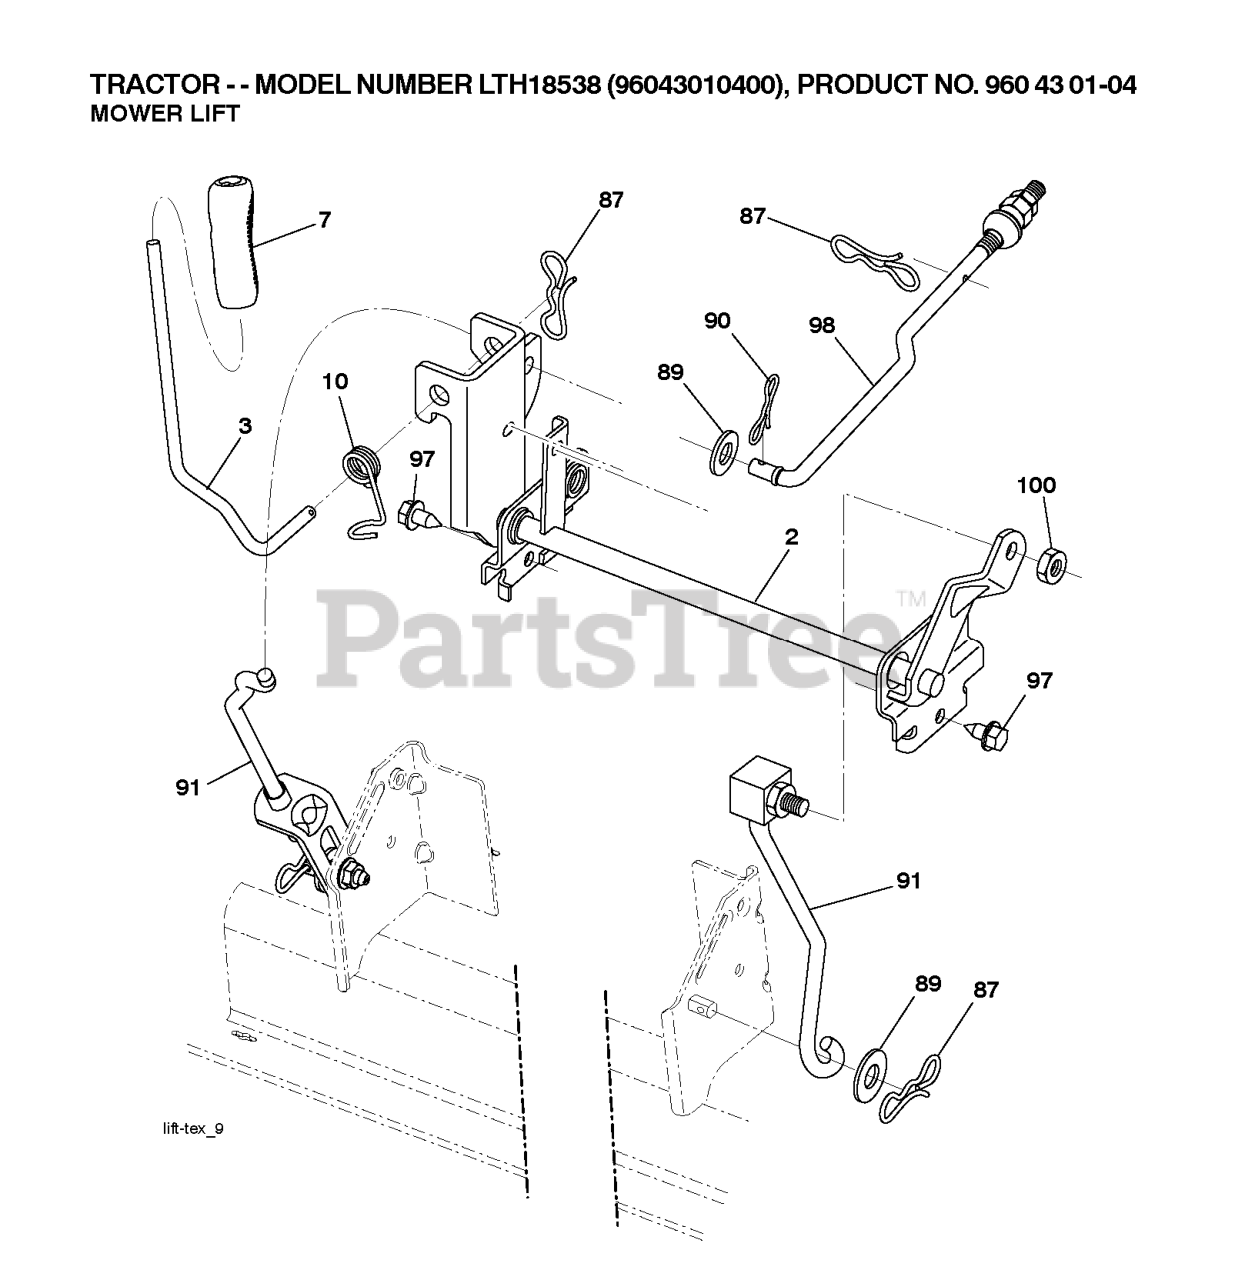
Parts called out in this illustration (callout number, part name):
2	SHAFT.ASM.CROSS.LIFT
3	LEVER.LIFT.HANDLE.LT
7	GRIP.HANDLE.LIFT.PVC.BLACK
10	SPRING.TORSION.LIFT.HANDLE
87	PIN.COTTER.7/16.BOW TI.
89	WASHER.CLEAR.ZINC
90	PIN.COTTER.5/16.BOW TI
91	LINK.ASM.LIFT.REAR
97	SCREW, 3/8-16X3/4
98	LINK.ASM.SUSP.FRONT.MW
100	LOCKNUT
101	LINK.ASM.LIFT.FIXE.38/42/46"
